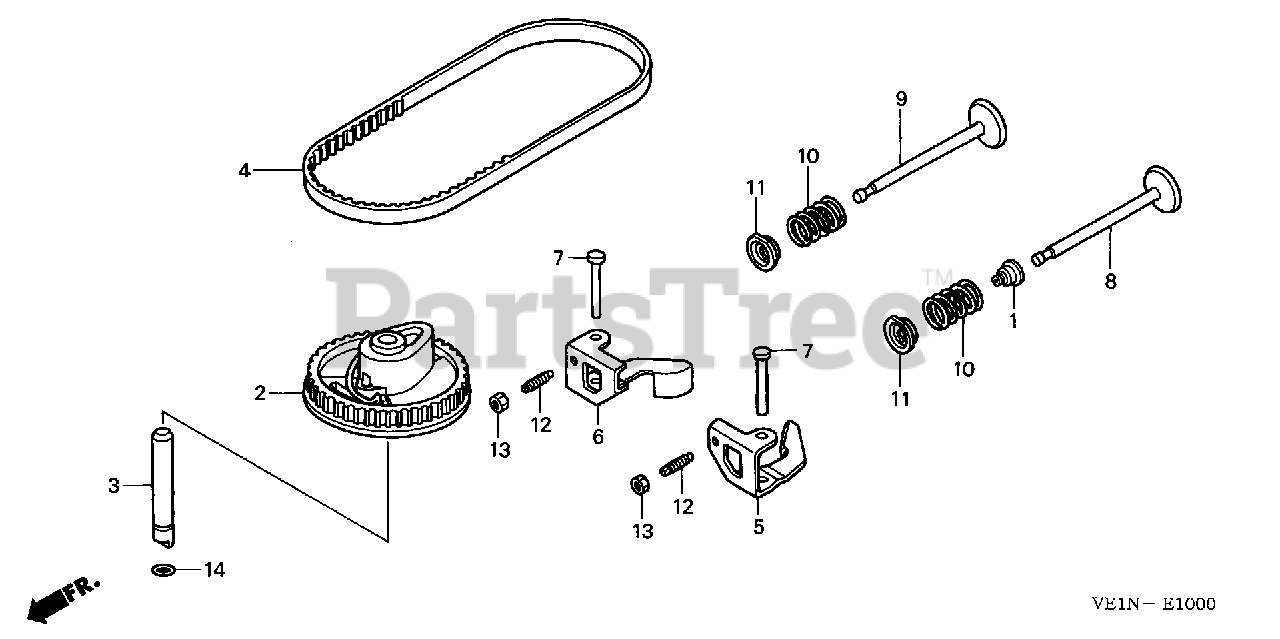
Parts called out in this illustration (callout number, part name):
1	SEAL, VALVE STEM
2	PULLEY, CAMSHAFT
3	SHAFT, CAM PULLEY
4	BELT, TIMING (84HU7 G-200)
5	ARM, IN. VALVE ROCKER
6	ARM, EX. VALVE ROCKER
7	SHAFT, ROCKER ARM
8	VALVE, IN. (TECHNOSTAR)
8	VALVE, IN. (ROCKNEL)
8	VALVE, IN.
9	VALVE, EX. (L8E)
10	SPRING, VALVE
11	RETAINER, IN. VALVE SPRING
12	SCREW, TAPPET ADJUSTING
13	NUT, TAPPET ADJUSTING
14	O-RING (6.8X1.9) (ARAI)
